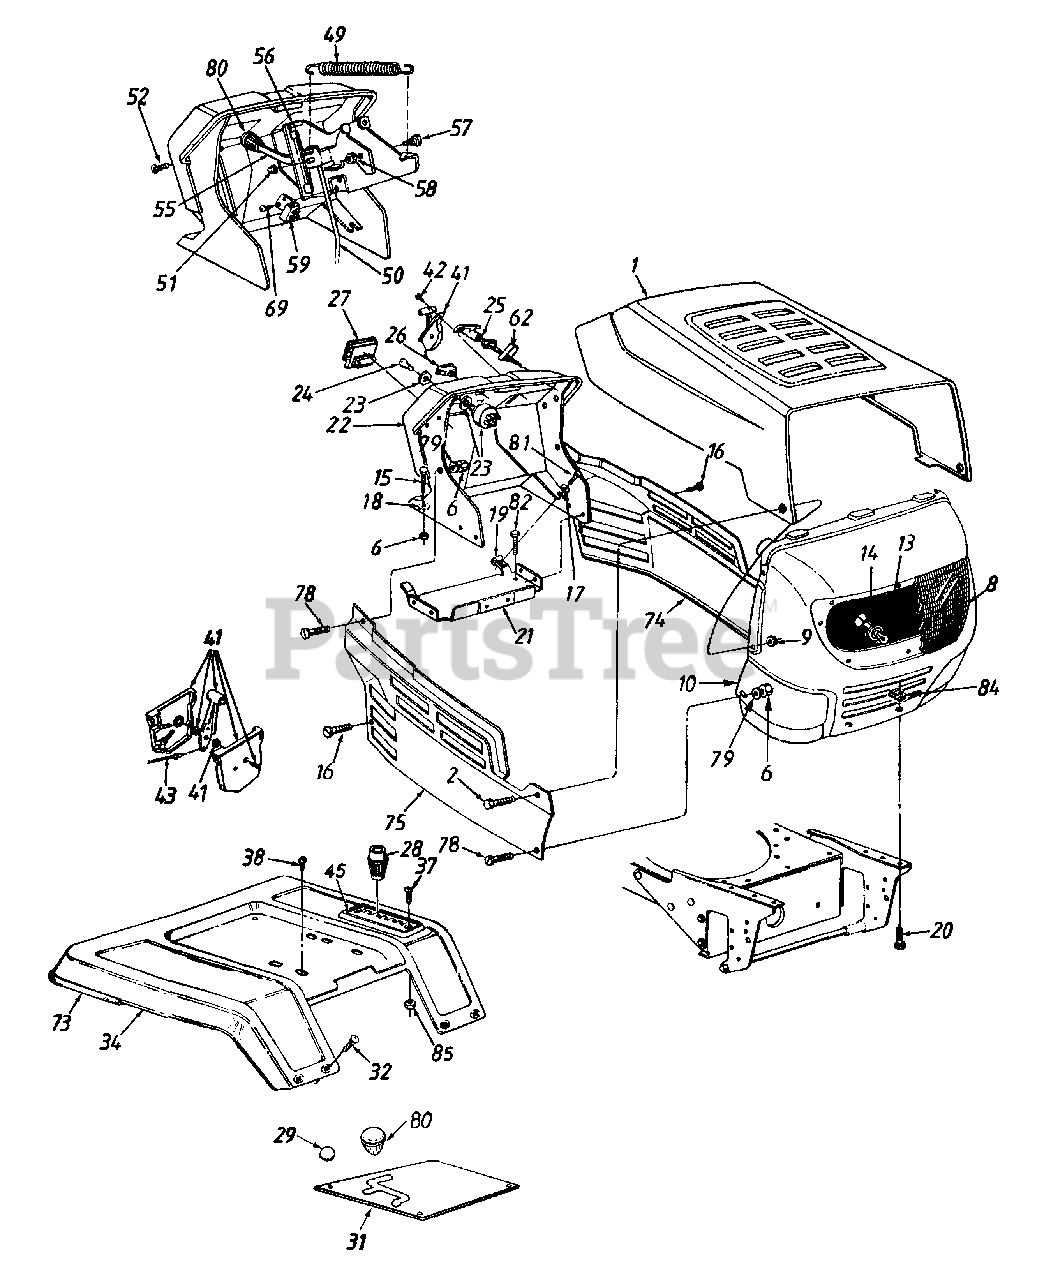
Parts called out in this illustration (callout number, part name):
6	Hex Nut 1/4-20 Thd.
8	Headlight Lens
9	Flange L-Nut 1/4-20 Thd.
13	Lamp
14	Socket
15	Carriage Bolt 1/4-20 x 1.0" Lg.
16	Hx Wash. Hd. TT-Tap Scr. 1/4-20 x .5" L
17	Fl-Wash. .281" I.D. x .73" O.D.
18	Bolt Retainer 1/4" I.D.
19	Speed Nut 1/4-20 Thd.
20	Hex Bolt 5/16-18 x .75" Lg.
23	Ignition Switch
24	Ignition Key
25	Choke Control
27	Ammeter
28	Shift Knob
38	Hx Wash Hd. AB-Tap Scr. 5/16 x .75" L
41	Throttle Box Ass'y.
42	Truss Mach. AB-Tap Scr. #10 x .5" Lg.
43	Throttle Control Wire 35" Lg.
45	6-Speed Selector Plate
49	Ext. Spring 5.06" Lg.
50	Deck Control Rod
51	Speed Nut 1/4" Rod
52	Torx Mach. Scr. 1/4 x .62" Lg.
55	PTO Lever
58	Hex L-Nut 5/16-18 Thd.
59	Safety Switch
62	Retainer Clip
69	Hx Wash. Hd. B-Tap Scr. #10 x .38" L.
73	Trim Strip 81" Lg.
79	Bell-Wash. 1/4" I.D.
80	Small Shift Knob
81	Hex TT-Tap Scr. 1/4-20 x .75" Lg.
82	Hex AB-Tap Scr. 1/4 x .62" Lg.
84	U-Nut 5/16-18 Thd.
85	Hex Sems Nut 1/4-20 Thd.
